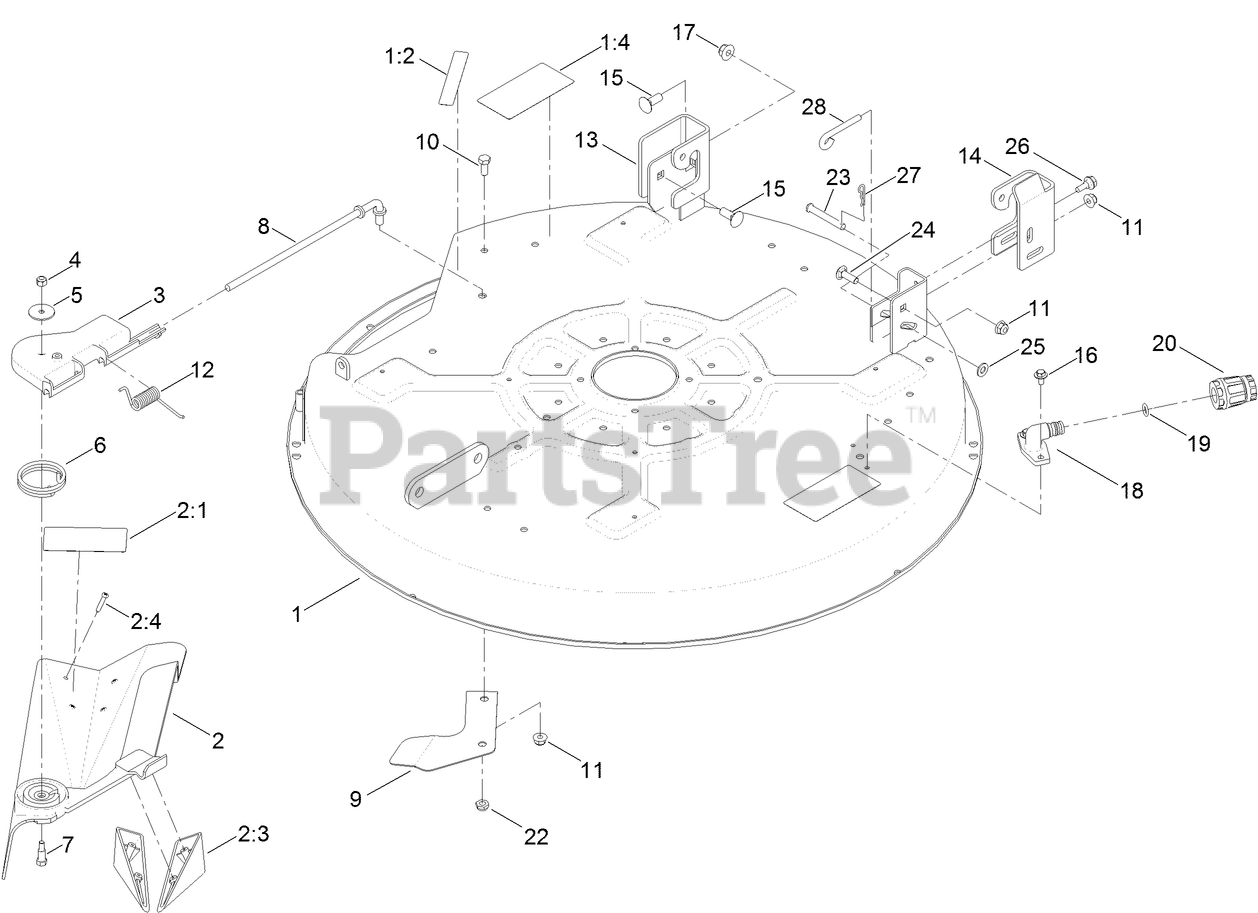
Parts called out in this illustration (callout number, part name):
1	32 INCH DECK AND DECAL ASM
1:2	DECAL-DANGER
1:4	DECAL-DANGER, DECK
2	32 INCH DEFLECTOR ASM
2:1	DECAL-DANGER
2:3	KICKER
2:4	SCREW-PPH
3	PIVOT-HINGE, DEFLECTOR
4	NUT-LOCK, NI
5	WASHER-FLAT
6	SPRING-TORSION
7	BOLT-SHOULDER
8	ROD-PIVOT
9	RAMP-DEFLECTOR
10	SCREW-HH
11	NUT-HF, NI
12	SPRING-TORSION
13	BRACKET-HANGER, RH
14	BRACKET-HANGER, LH
15	BOLT-CARR
16	SCREW-HHFTF
17	NUT-HF, NI
19	O-RING
20	CONNECTOR-HOSE
23	PIN-CLEVIS
24	SCREW-CARR
25	WASHER-PLAIN
26	SCREW-SHOULDER,HWH
27	PIN-COTTER
28	ROD-LEVEL, DECK
